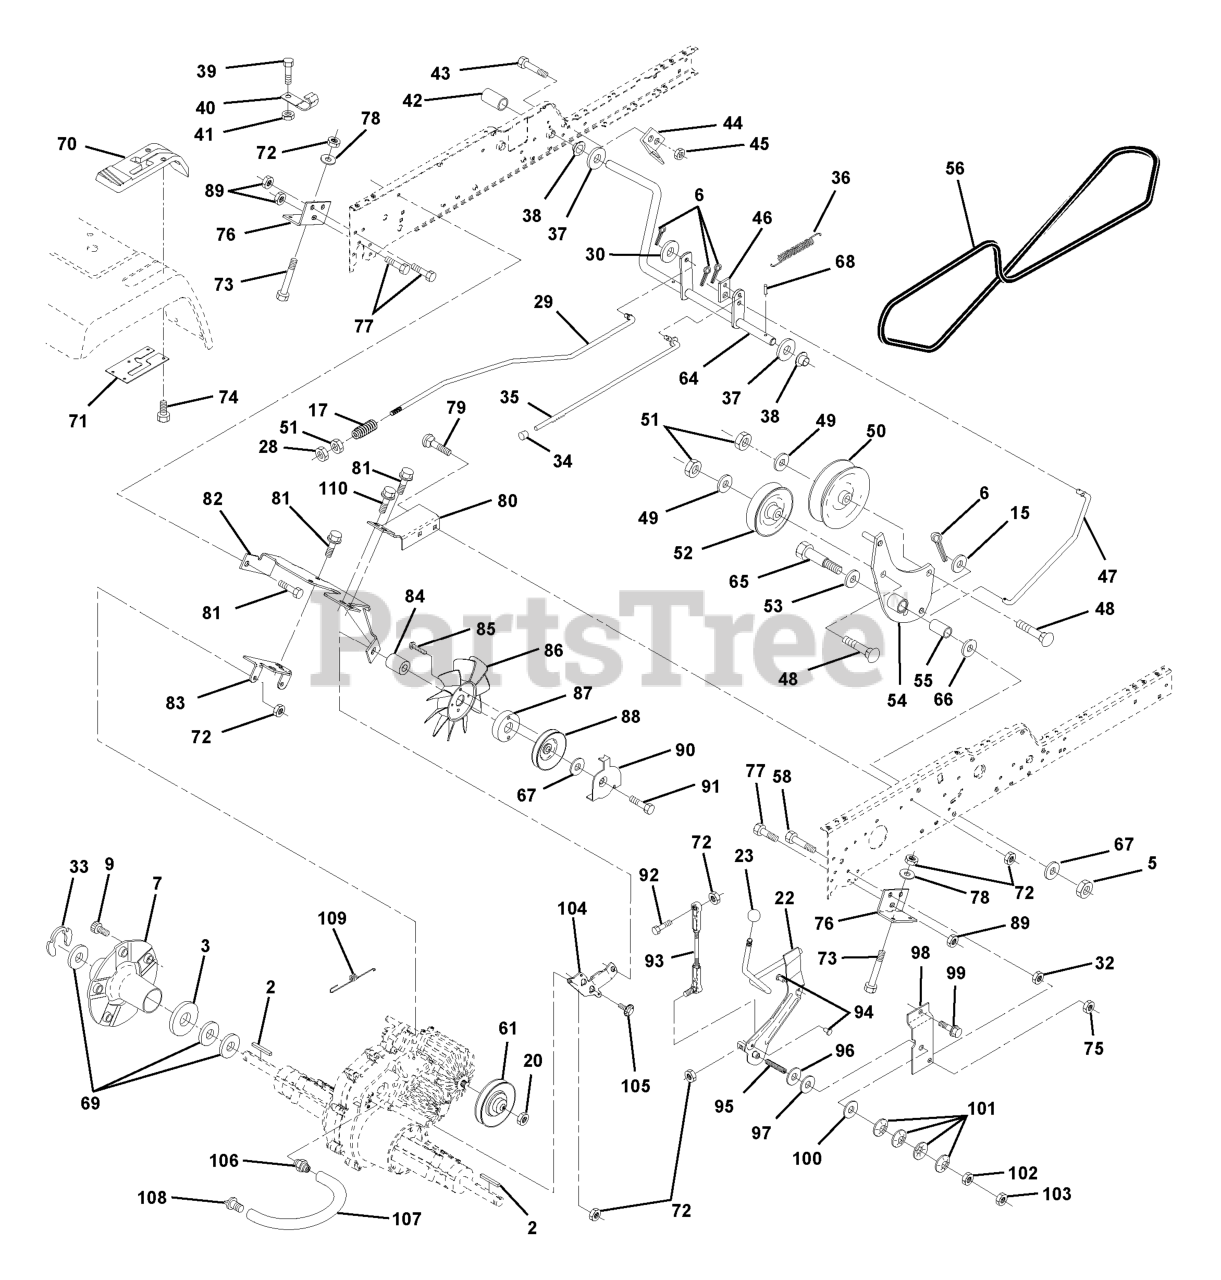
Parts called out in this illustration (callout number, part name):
2	KEY 1/4 X 2.5
6	COTTER PIN
7	HUB ASMBLY
9	HUB BOLT
15	WASHER
17	SPRING.ROD.BRAKE
20	NUT.HEX.1/2-20
22	SHAFT ARM ASMBLY
23	KNOB.DELUXE.(PISTOL.GRIP).BLAC
28	NUT
30	WASHER
33	E RING HYT
34	PLUNGER CAP
35	PARKING BRAKE ROD
36	SPRING DRIVE GROUND
39	Screw Fin #10-24 x 1
40	ACT-SWITCH T
41	LOCKNUT
42	COVER, PEDAL (1 2)
43	BOLT.HEX.1/4.X.3/4.DICHROMATE
44	BRKT SWITCH GT
45	LOCKNUT.NYLOC.1/4-20
46	RETAINER SPRING
47	CLUTCH ROD
49	Washer 13/32 x 7/8 x 13 Ga
50	FLAT IDLER PULLEY
51	NUT
52	PULLEY.IDLER.V.
54	CLUTCH ARM ASSY
55	BEARING LT (2 2)
58	BOLT.HEX.7/16-14.FINISHED
64	SHAFT CLUTCH/BRAKE PEDAL
66	WASHER.BLADE
67	WASHER
68	ROLL PIN STD
70	CONSOLE, SHIFT HYD
71	PLATE CONSOLE SHIFT
72	NUT.71038.31-18.HEX.NYLOCK
73	Bolt Fin Hex 5/16-18 x 3
74	SCREW.HI-LO.CONSOLE
75	Nut Lock Hex 7/16
76	BRACKET TRANSAXLE
77	BOLT
79	BOLT.CARR.5/16-18X5/8.SHORT
80	TORQUE BRACKET RH
81	SCREW
82	BRACKET MOUNT TORQUE/FAN
83	STRAP TORQUE MID
85	Screw #10-24 x 1-1/4
86	FAN 7" HYDRO
87	ADAPTOR.FAN.TRANSAXLE.VGTH
88	IDLER PULLEY
89	Nut, Crownlock 7/16-14
90	KEEPER.BELT
91	SCREW.HXWSH.3/8
92	BOLT
93	LINK ASM SHIFT
94	FASTENER.XMAS.TREE
95	Screw Set 5/16-18 x 1.75
98	SHIFT BRACKET
99	SCREW LT
102	NUT
103	JAM NUT TI
104	BRACKET IDLER
105	SCREW CRT
106	O-RING KIT 70110
107	LINE.VENT.HYDRO-GEAR
108	CAP, VENT ASSY
109	RETURN SPRING
110	HINGE SCREW
